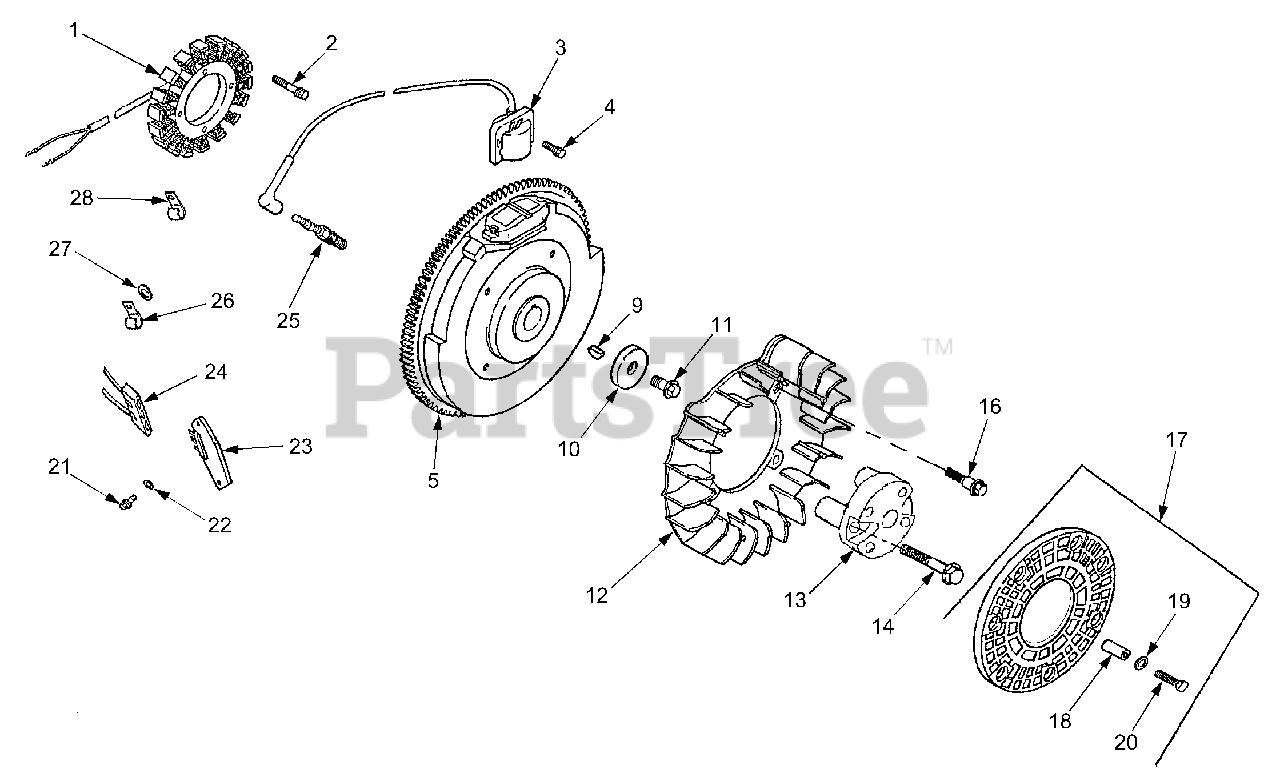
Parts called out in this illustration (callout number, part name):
1	Kit, 15 Amp Stator
2	Screw, Hex Cap M5 x 0.8 x 25
3	Module, Ignition
4	Screw, Hex Socket Hd. M5 x 0.8 x
5	Flywheel
10	Washer, Plain 3/8"
11	Screw, Hex Flange M10 x 1.5 x 46
12	Fan
13	Adapter, Drive Shaft
14	Screw, Hex Flange M10 x 1.5 x 90
16	Bolt, Shoulder, M6 x 1.0 x 16
17	Kit, Grass Screen
19	Washer, Plain 3/16"
20	Screw, Hex Cap M4 x 0.7 x 25
21	Screw, Phillips Hd. 11-16 x 7/8"
22	Washer, Plain 3/16"
23	Rectifier-regulator 15 Amp
24	Connector (3 Contact)
25	Spark Plug
26	Clip, Cable
27	Washer, Plain 1/4"
